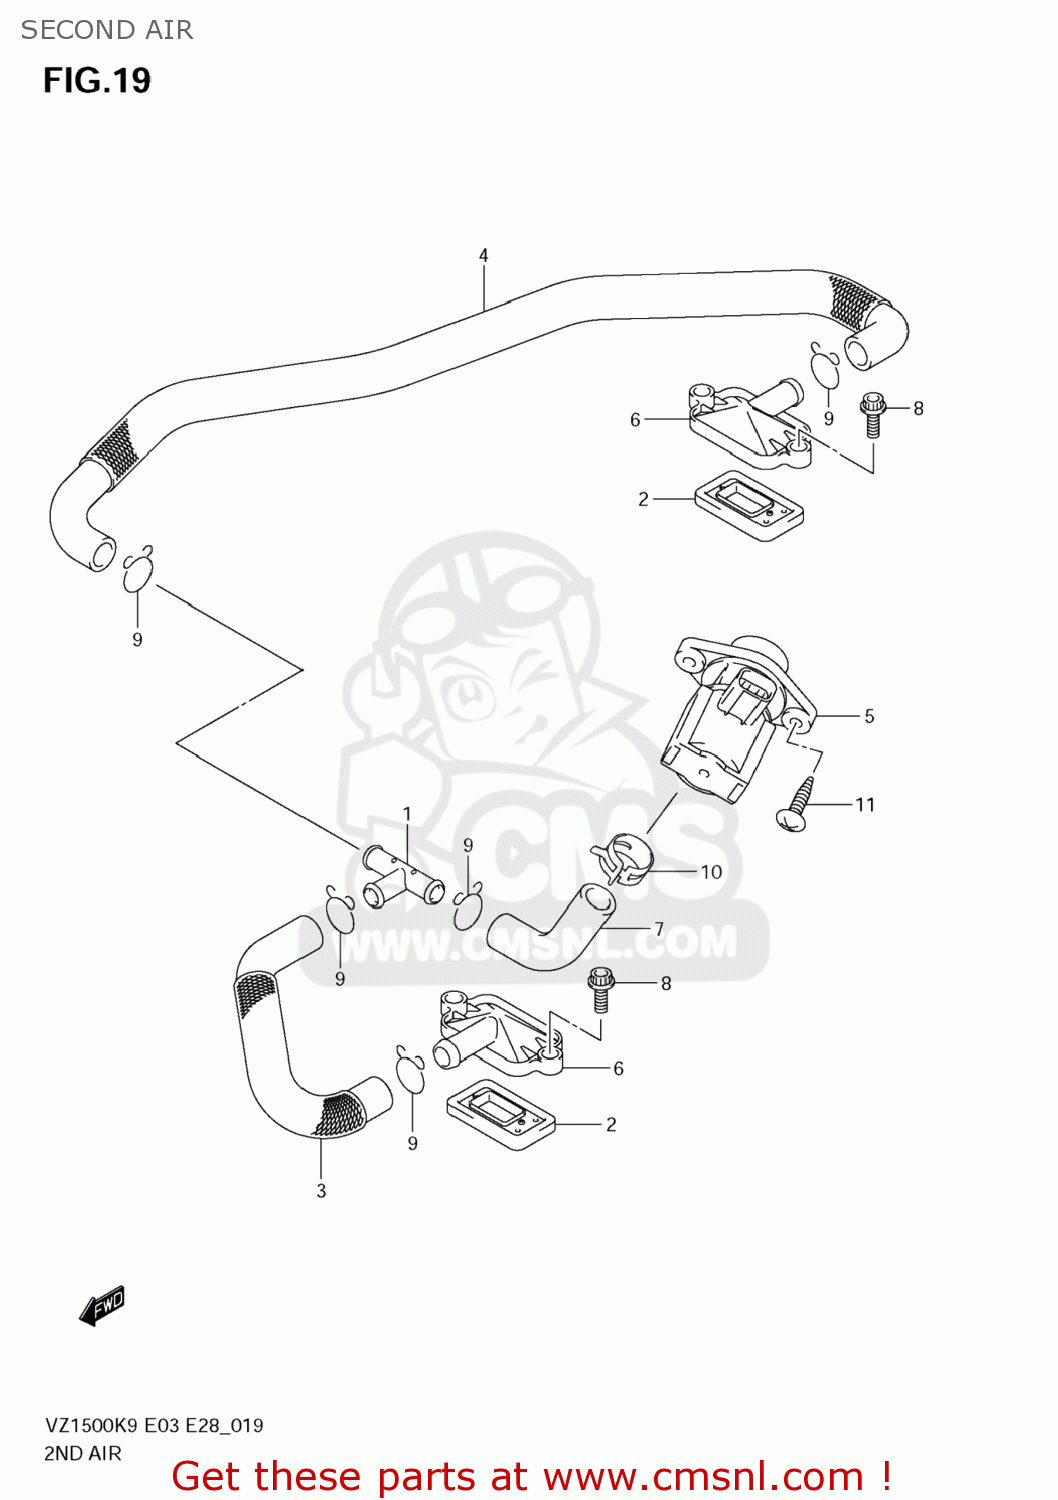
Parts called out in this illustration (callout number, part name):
1	JOINT
2	VALVE ASSY,2ND AIR REED
3	HOSE,2ND AIR VALVE FR
4	HOSE,2ND AIR VALVE RR
5	VALVE ASSY,AIR CUT
6	COVER,2ND AIR REED VALVE
7	HOSE,2ND AIR VALVE
8	BOLT(6X18)
9	CLIP
10	CLIP
11	SCREW
